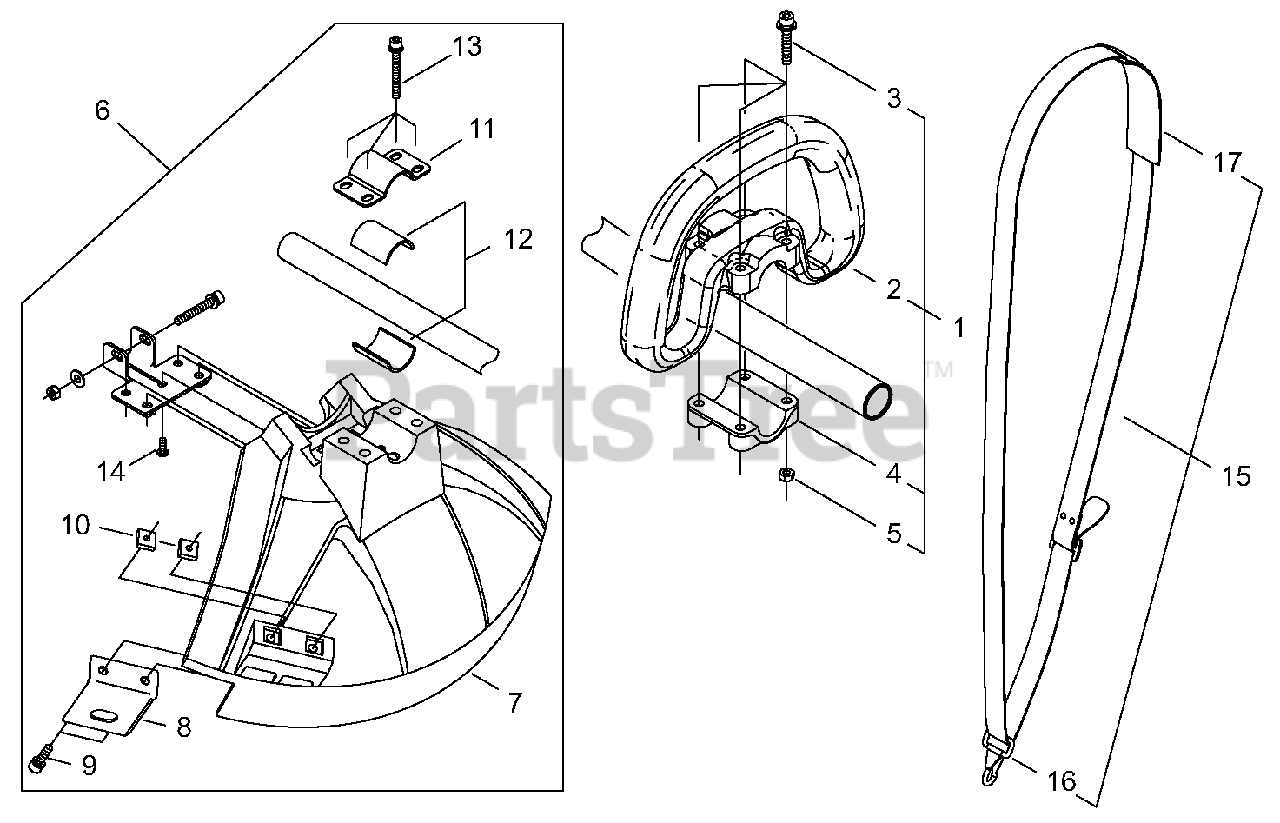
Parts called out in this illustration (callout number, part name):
1	FRONT HANDLE ASSY
2	HANDLE, FRONT
3	BOLT
4	BRACKET, MOUNTING
5	NUT M5
6	DEBRIS SHIELD KIT - PLASTIC
7	SHIELD, DEBRIS
8	CUTTER
9	BOLT M5×16
10	NUT M5
11	CLAMP, UPPER
12	SPACER 24
13	BOLT M5×45
14	SCREW HILO 4×10
15	HARNESS ASSY
16	HOOK, SNAP
17	PAD, SHOULDER
